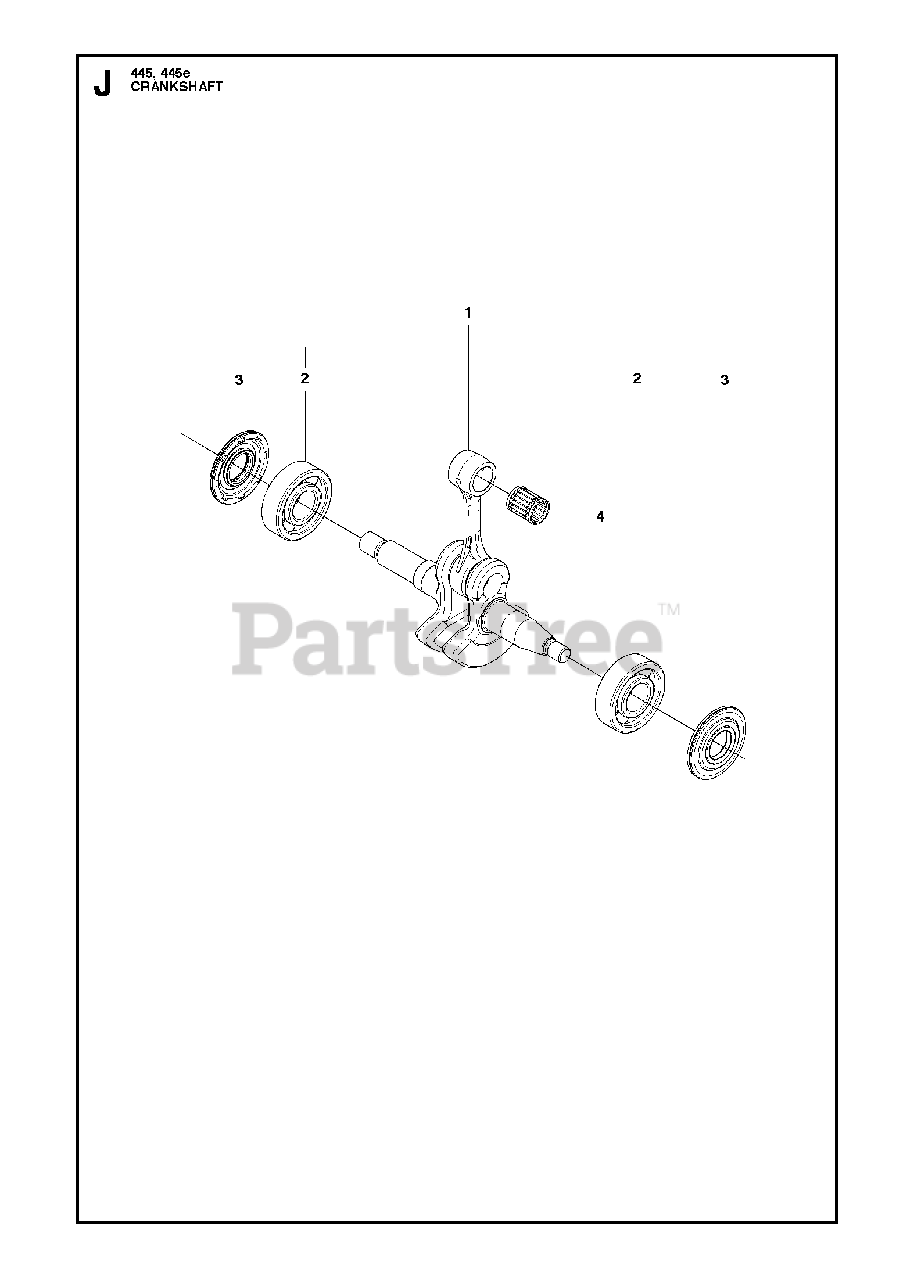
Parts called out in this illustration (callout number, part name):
1	CRANKSHAFT ASSY
2	BEARING
3	SEALING
4	NEEDLE BEARING
